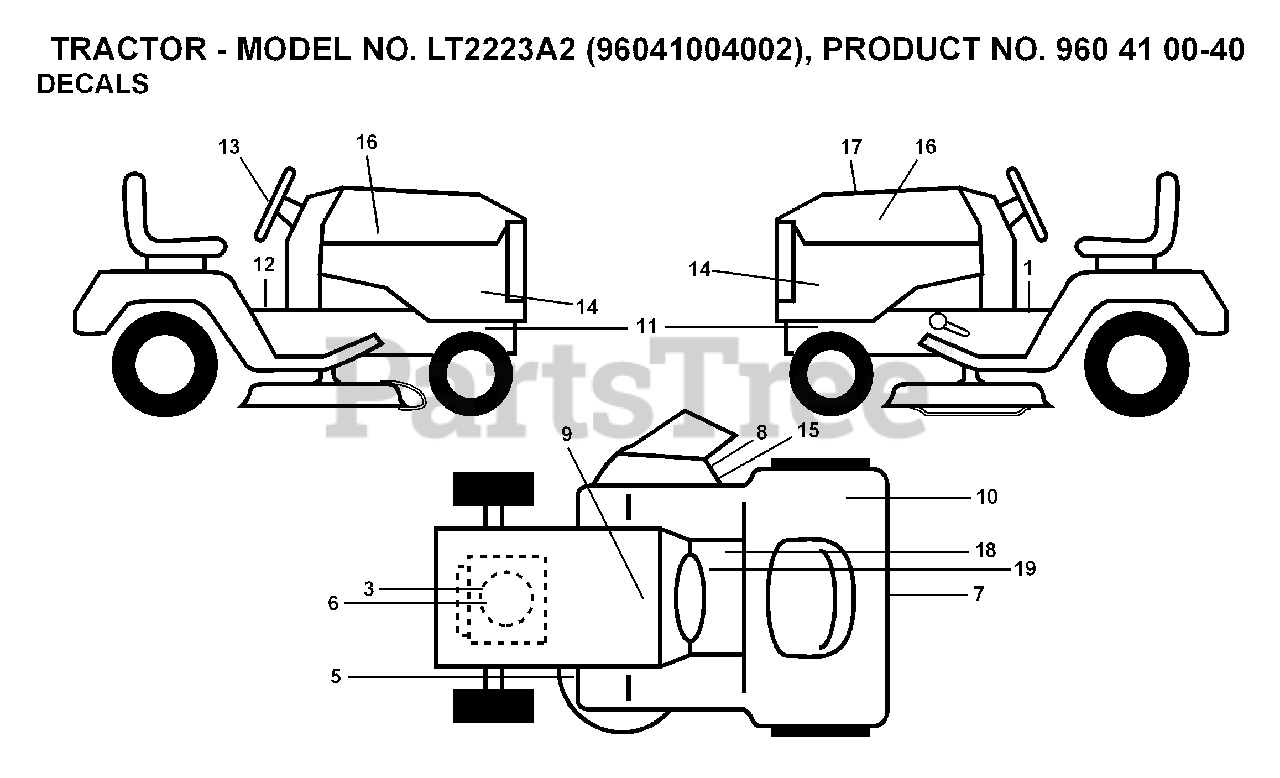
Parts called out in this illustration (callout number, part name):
1	DECAL PARK BRAKE
5	DECAL V BELT SCHEMATIC
7	DECAL.80 DBA.AUSTRALIA
8	DECAL, DEFLECT WARNING
12	DECAL.INTERNATIONL.CUTFINGER
15	DECAL BTRY SYMBOLS
